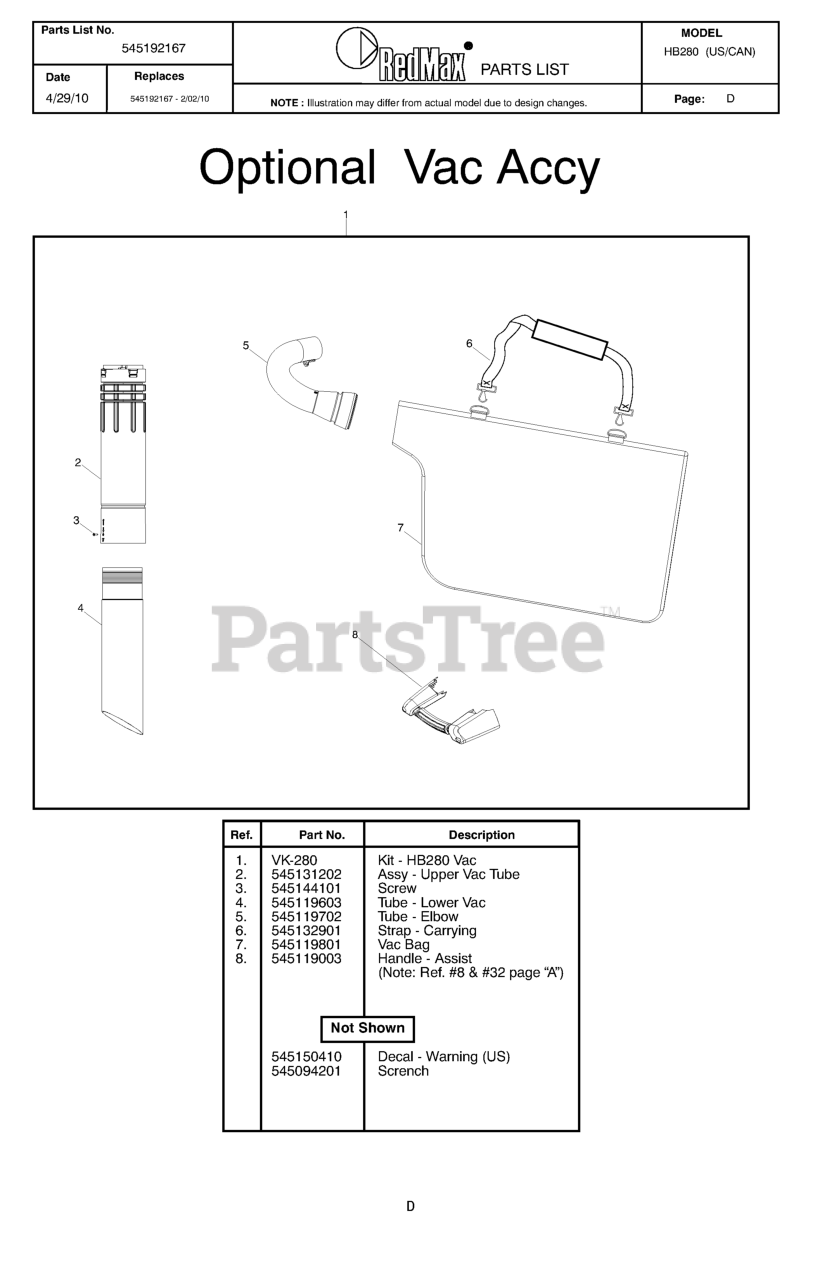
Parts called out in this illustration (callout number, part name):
1	KIT-HB280VAC
2	ASSY - UPPER VAC TUBE
4	TUBE - LOWER VAC
5	TUBE - ELBOW
6	STRAP - CARRYING
7	VAC BAG
8	HANDLE - ASSIST
NI	DECAL - WARNING (US)
NI	SCHRENCH
